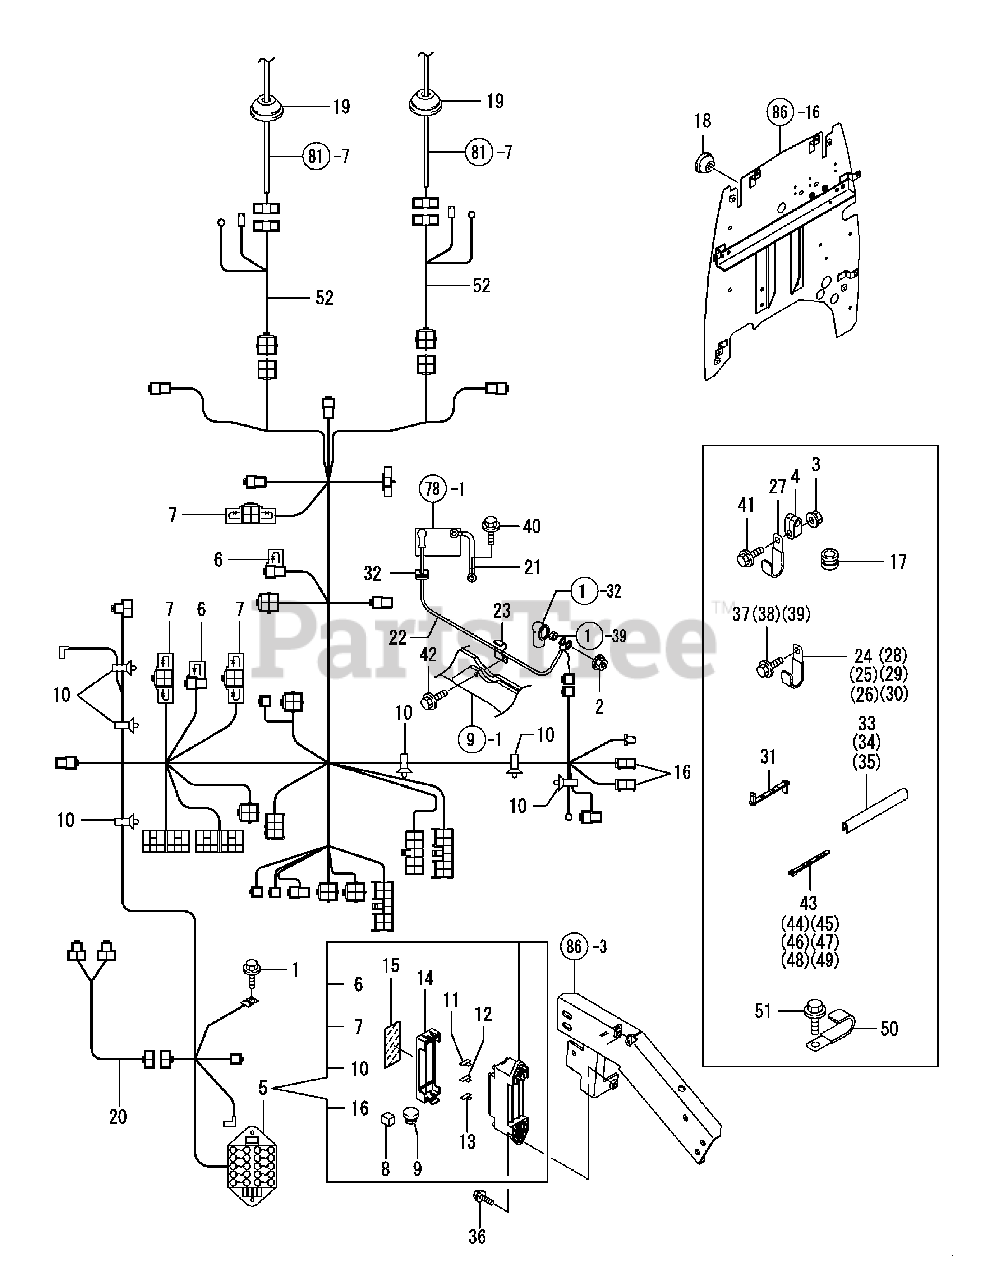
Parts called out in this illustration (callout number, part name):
1	BOLT M 8X 12 PLATED
2	NUT W/WASHER 8
3	NUT W/WASHER 8
4	CLAMP,CHAFF WIRE
5	WIRING HARNESS A CMP
14	COVER, FUSE BOX
16	BLOW 79A,SLOW CMP
17	GROMMET 25
18	GROMMET 25
19	GROMMET 25
20	WIRING HARNESS,
21	CABLE,BATTERY EARTH
22	CABLE, BATTERY
23	CLAMP, B.CABLE
24	CLAMP, WIRE HARNESS
25	CLAMP, WIRE HARNESS
26	CLAMP, WIRE HARNESS
27	CLAMP, WIRE HARNESS
28	CLAMP, WIRE HARNESS
29	CLAMP, WIRE HARNESS
30	CLAMP, WIRE HARNESS
32	GROMMET, CABLE
35	COVER,HOSE PROTECTOR
36	BOLT M 6X 16 PLATED
37	BOLT M 8X 12 PLATED
38	BOLT M 8X 12 PLATED
39	BOLT M 8X 16 PLATED
40	BOLT M 8X 16 PLATED
41	BOLT M 8X 25 PLATED
42	BOLT M 8X 35 PLATED
50	CLAMP, WIRE HARNESS
52	WIRING HARNESS C CMP
